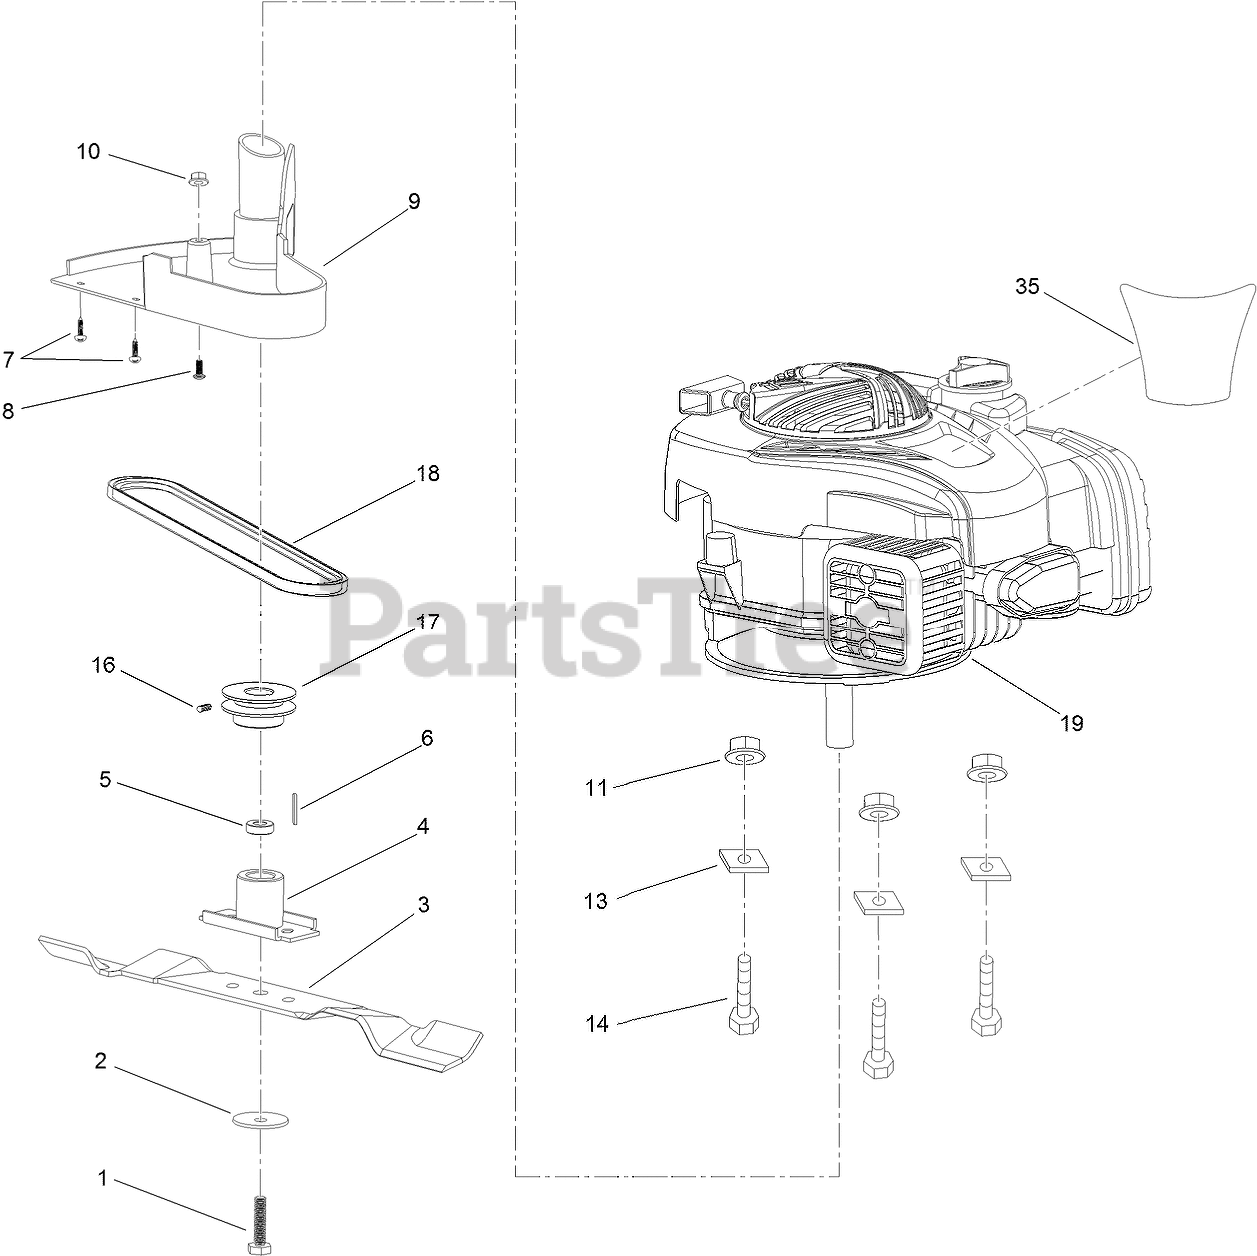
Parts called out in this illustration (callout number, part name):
1	BOLT-BLADE
2	WASHER-DISHED
3	BLADE-MULCH
4	SUPPORT-BLADE
5	SHEATH-BLADE
6	KEY-FLAT
7	SCREW-SELF DRIVING
8	SCREW-TOOTH
9	COVER-PULLEY, BELT
10	NUT-LOCK, FLANGE
11	NUT-LOCK, FLANGE
13	WASHER-SQUARE
14	BOLT-BLADE
16	SCREW-GRUB
17	PULLEY-DRIVE
18	BELT-TRIANGLE
19	ENGINE-BRIGGS STRATTON, 500E STAGE V
35	DECAL-SHROUD
